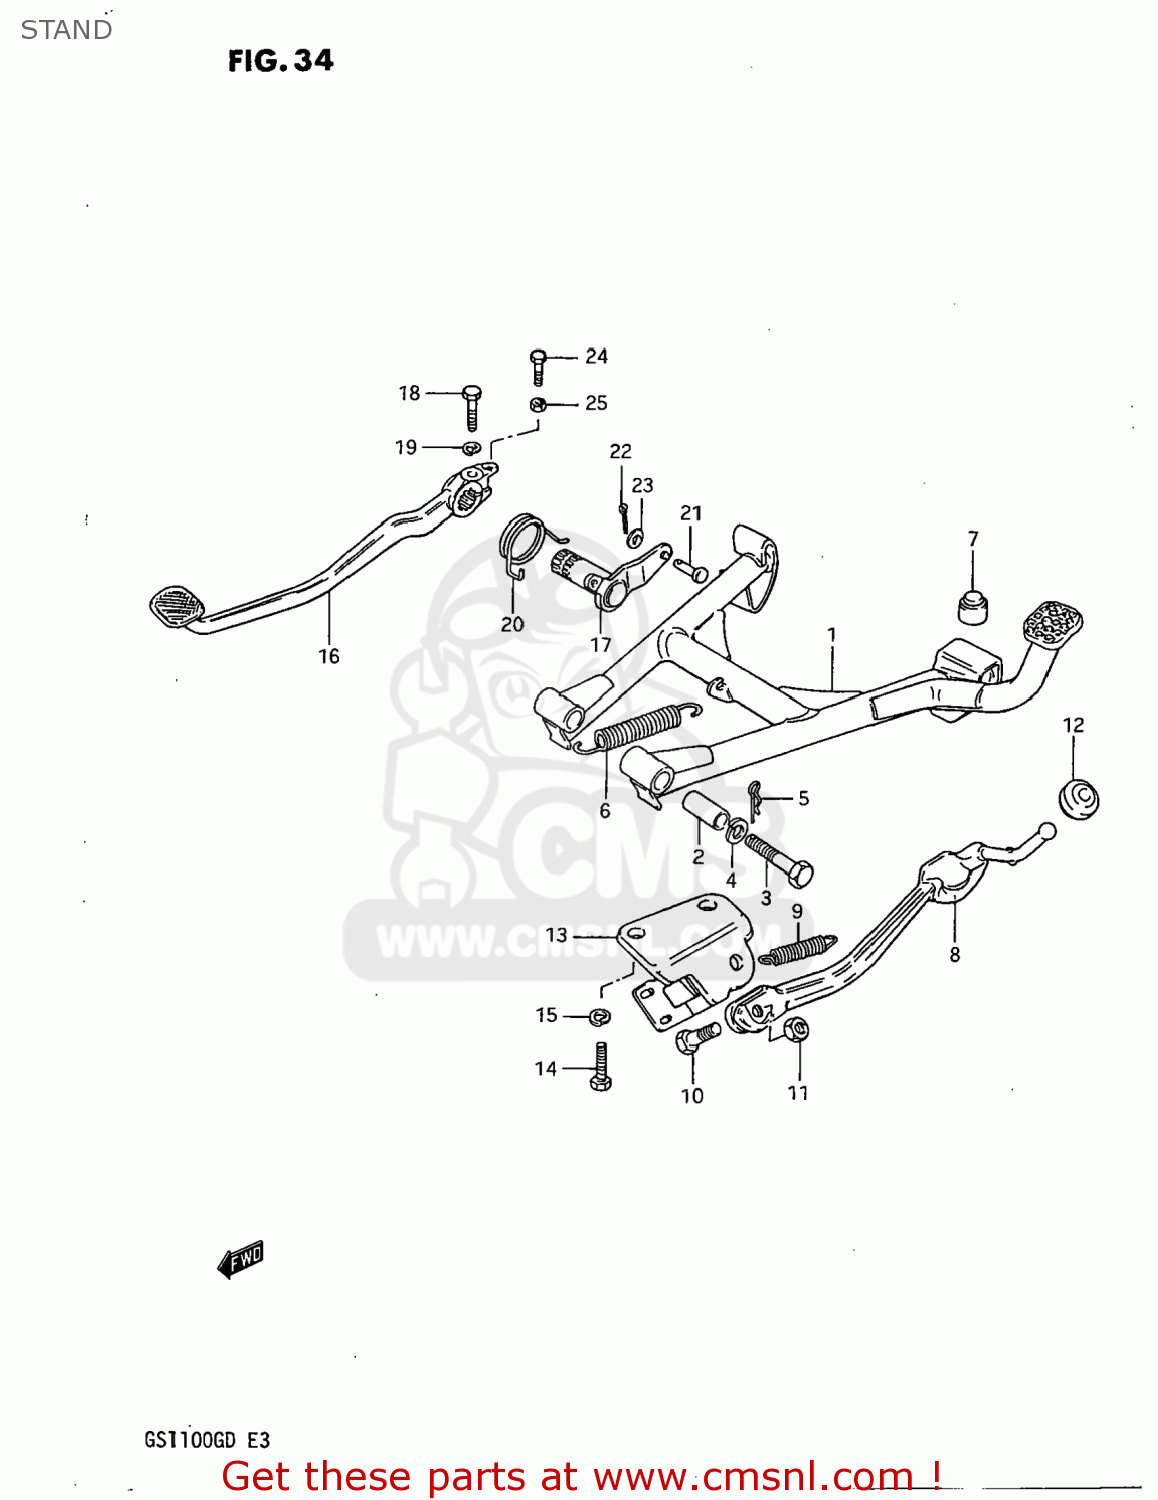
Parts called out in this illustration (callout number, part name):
1	STAND,CENTER
2	SPACER(10X16X38.8)
3	BOLT
4	LOCK WASHER
5	CLIP
6	SPRING
7	CUSHION
8	STAND,SIDE
9	SPRING
10	BOLT(10X30)
11	NUT
12	CUSHION
13	BRACKET,SIDE STAND
14	BOLT
15	LOCK WASHER
16	PEDAL,BRAKE
17	ARM,BRAKE PEDAL ROD
18	BOLT
19	LOCK WASHER
20	SPRING
21	PIN
22	PIN
23	WASHER
24	BOLT
25	NUT
